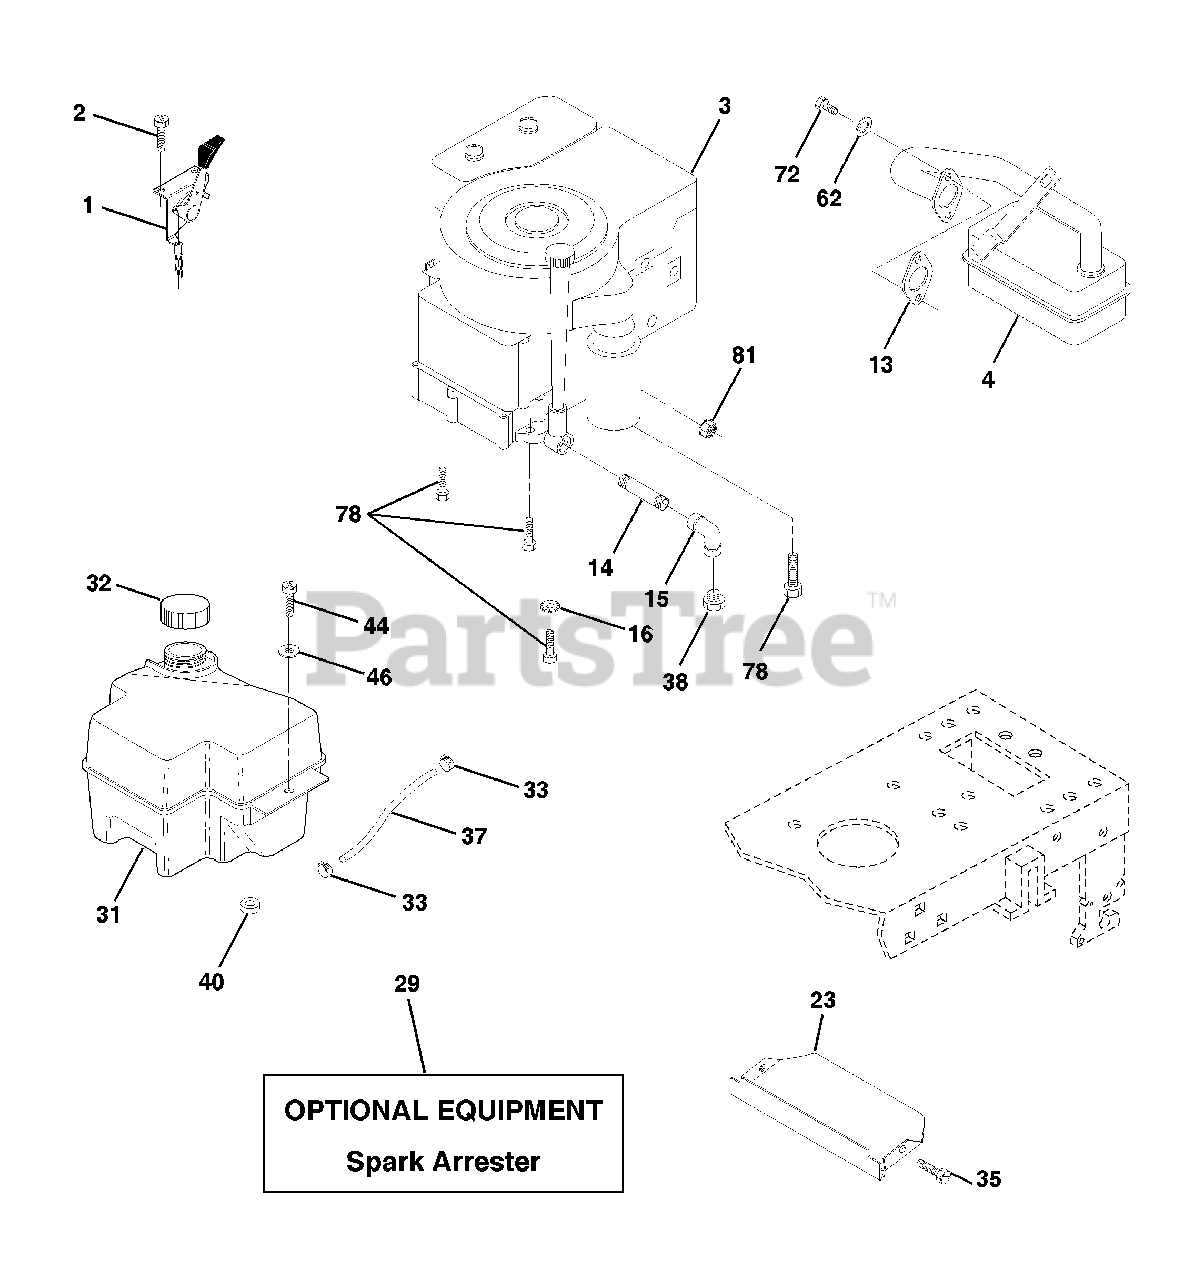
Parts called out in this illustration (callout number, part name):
1	Control Th/ch 23 5 LH Flag
2	Screw Hex Thd Cut 1/4-20 x 5/8 T
4	Muffler LT B&S 14.5
13	Gasket Eng 1 313 Id Tin Plated
14	Nipple Pipe 3/8 Npt X 3"
15	Elbow Std 90 Degree 3/8-18 Npt
16	Washer Lock Ext Tooth 3/8
23	Shield Brn/Dbr Guard
29	Kit Spark Arrestor
31	Tank Fuel Front 2 00
32	Cap Asm Fuel W/sym Vented
33	Clamp Hose Black
35	Screw
37	Line Fuel 20"
38	Plug Oil Drain
40	Bushing Snap Nyl Blk Fuel Line
44	Screw Hexwsh Thdrol 1/4-20x3/4
46	Washer 9/32 x 7/8 x 16 Ga
62	Washer Lock Hvy Hlcl Spr 5/16
72	Screw Hexhd Cap 5/16-18x 3/4
78	Screw Thdrol 3/8-16 x 1-1/4 TYTT
81	Nut Flange 1/4-20 Starter Nut
